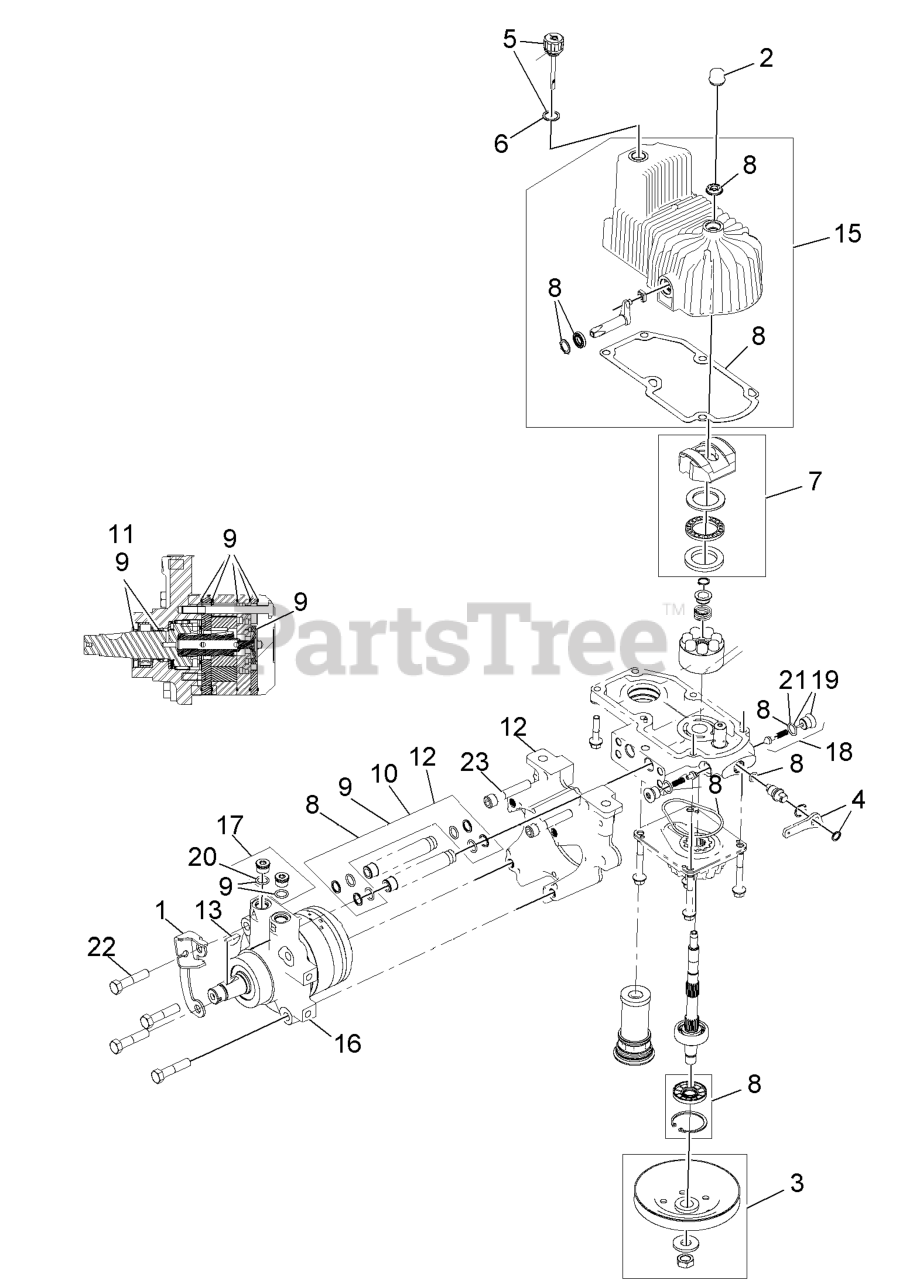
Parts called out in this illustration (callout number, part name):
1	BRACKET-ANCHOR, CABLE
2	COVER-SHAFT, HYDRO
3	PULLEY KIT
4	HANDLE-BYPASS VALVE, HYDRO
5	DIPSTICK-HYDRO W/GASKET
6	GASKET-DIPSTICK, HYDRO
7	SWASH BLOCK KIT
8	PUMP SEAL KIT
9	MOTOR SEAL KIT
10	TUBE SEAL KIT
11	OUTPUT SHAFT SEAL KIT
12	NOSE CUP-UHT
13	KEY-WOODRUFF
15	HOUSING-HYDRO, RH
16	MOTOR-HYDRAULIC RH 240CC
17	MAGNETIC PLUGS SERVICE KIT
18	CHECK VALVE ASM
19	PLUG-CHECK (W/O-RING)
21	O-RING-CHECK VALVE
22	SCREW HH
23	SCREW-HSH
